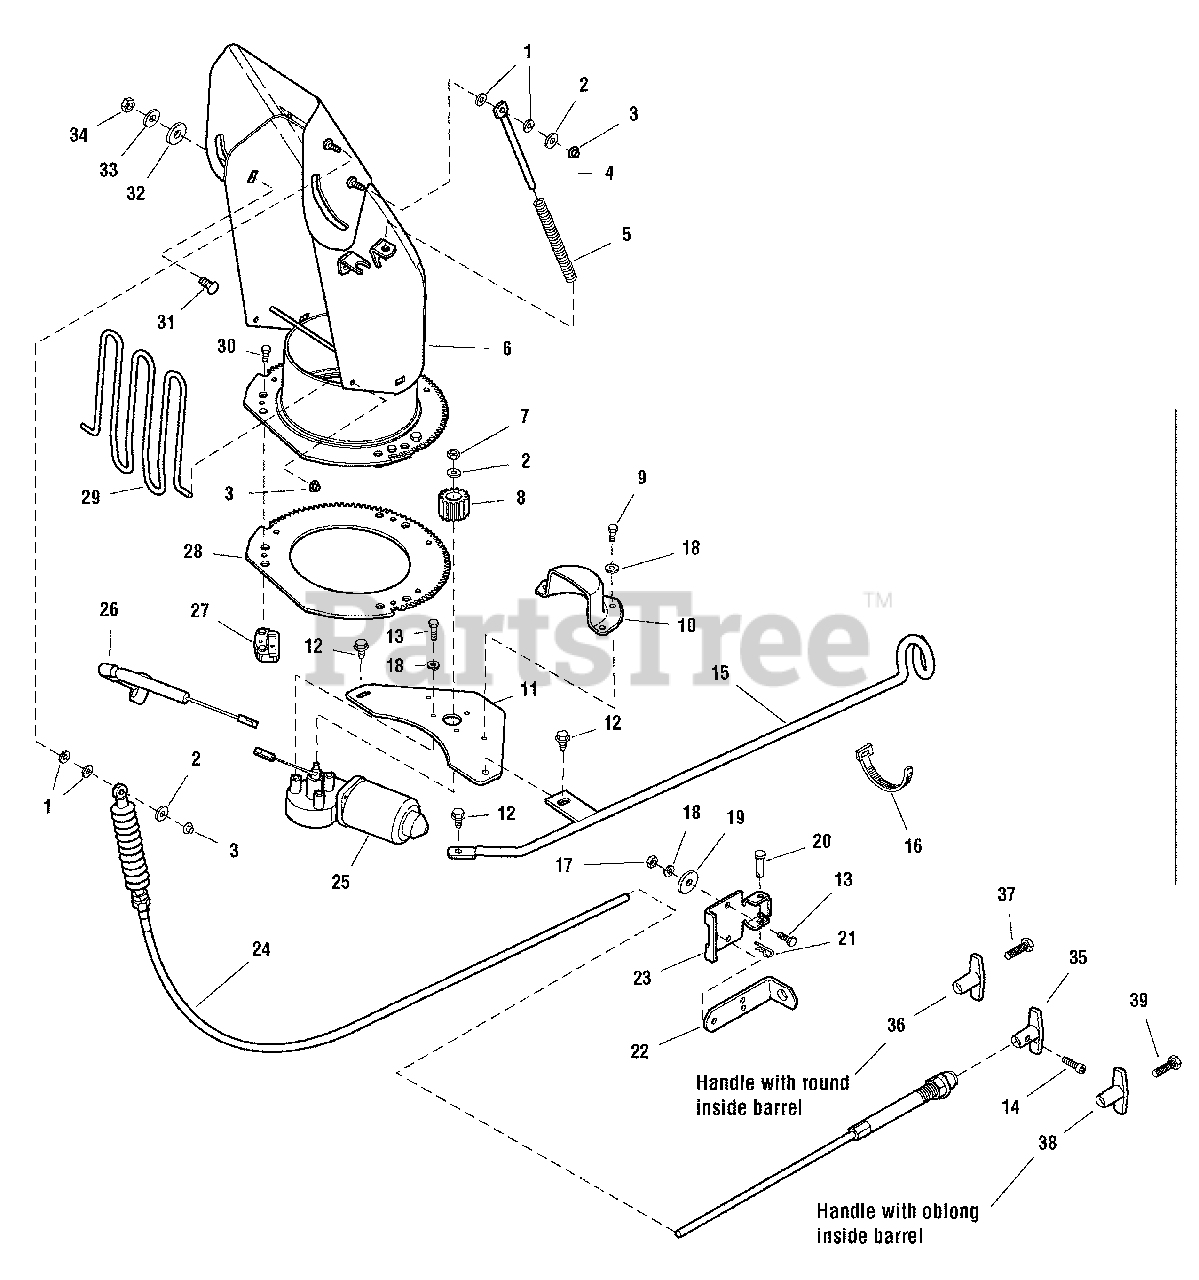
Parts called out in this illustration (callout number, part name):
2	WASHER
3	NUT PUSH, Capped, 1/4
5	SPRING, Compression
6	CHUTE & DEFLECTOR ASSEMBLY
7	LOCKNUT, Hex, 1/4-20
8	PINION, 15 Theeth
9	SCREW, Hex Head, Taptite, 1/4-20 x 1/2
11	PLATE, Motor Mounting
12	SCREW, Hex Head, Taptite, 1/4-20 x 5/8
13	CAPSCREW, Hex Head, 1/4-20 x 7/8
14	SCREW, Set Hex, #10-24 x 3/8
15	ROD & TAB ASSEMBLY
16	TIE, Self Locking
17	NUT, Hex, 1/4 x 20 ESNA
19	WASHER
20	PIN, Flat Head, Drilled, SS
21	CLIP, Hair Pin
24	CABLE & KNOB ASSEMBLY
25	MOTOR, Electric
26	HARNESS ASSEMBLY
28	GEAR, Chute
29	GUARD & SUPPORT ASSEMBLY
30	SCREW, Hex Head,# 10-14 x 5/8
31	CARRIAGE BOLT, 5/16-18 x 3/4
34	LOCKNUT, Hex, ESNA, 5/16-18
36	HANDLE "T"
37	SCREW, Round Head
38	HANDLE "T"
39	SCREW, #8c x 3/4
